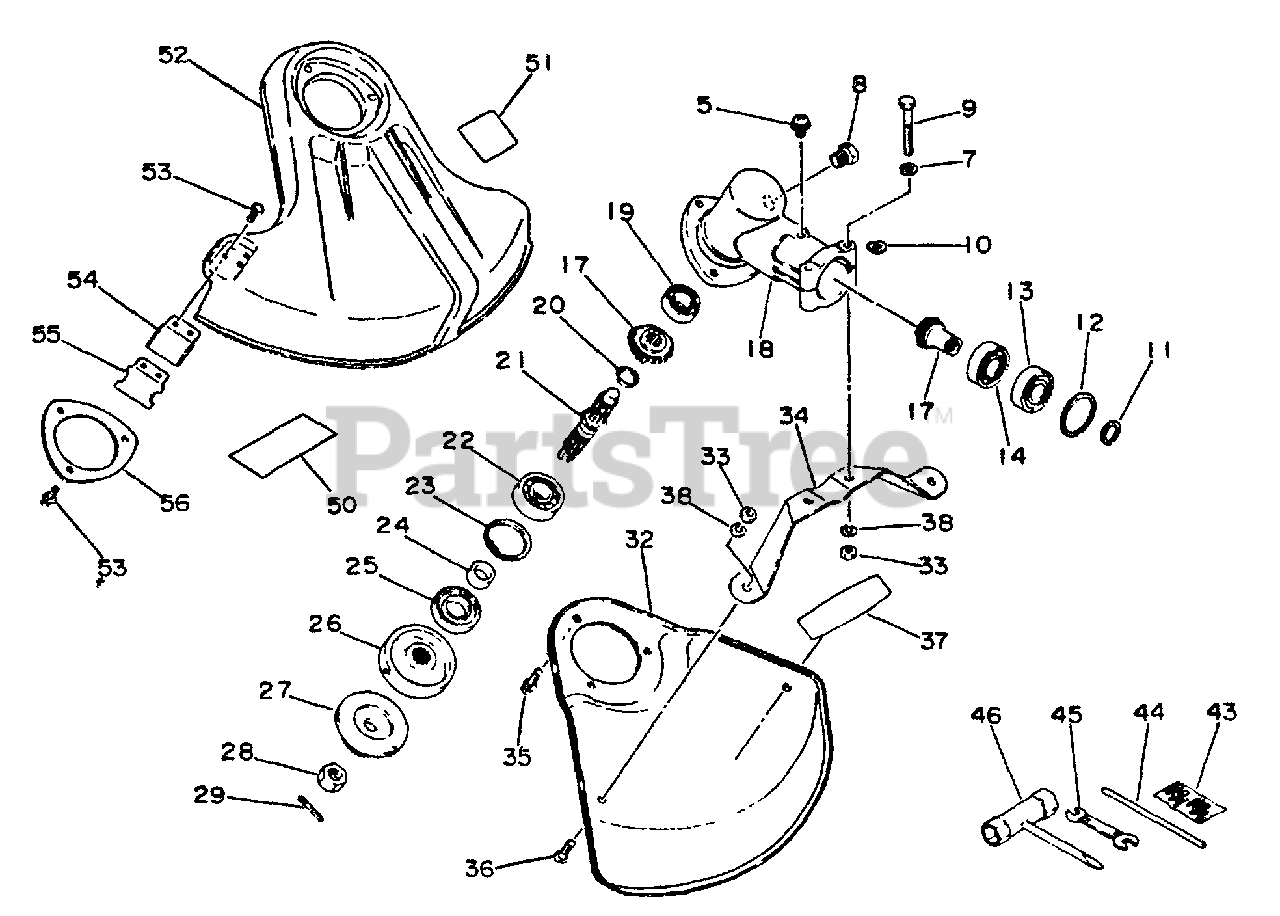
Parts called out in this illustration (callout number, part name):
5	SCREW - 5X10
7	WASHER - 5
8	BOLT - 8X8
9	BOLT - 5X40
11	RING, RETAINING - 12
12	RING, RETAINING - 28
13	BEARING, BALL - 6001
14	BEARING, BALL - 6001
17	GEAR SET - BEVEL
18	CASE, GEAR
19	BEARING, BALL - 6000
20	RING, RETAINING - 12
21	GEAR - SHAFT
22	BEARING, BALL - 6201
23	RING, RETAINING - 32
25	SEAL, OIL
26	ADAPTOR, BLADE - UPPER
27	ADAPTOR, BLADE - LOWER
28	NUT - 10 -- LEFT HAND
29	PIN, SPLIT - 2X22
32	SHIELD
34	BRACKET, SHIELD
35	SCREW - 5X10
36	SCREW - 5X8
37	LABEL - ECHO
38	LOCKWASHER - 5
43	PIN, SPLIT - 2X22
44	LOCKING TOOL
45	SPANNER - 8X10mm
46	T-WRENCH - 17X19mm
50	LABEL - ECHO
51	LABEL - CAUTION
52	SHIELD, DEBRIS - PLASTIC
53	KNIFE, TRIMMER LINE
54	GUARD
55	SCREW - 5X16
56	PLATE, SHIELD
